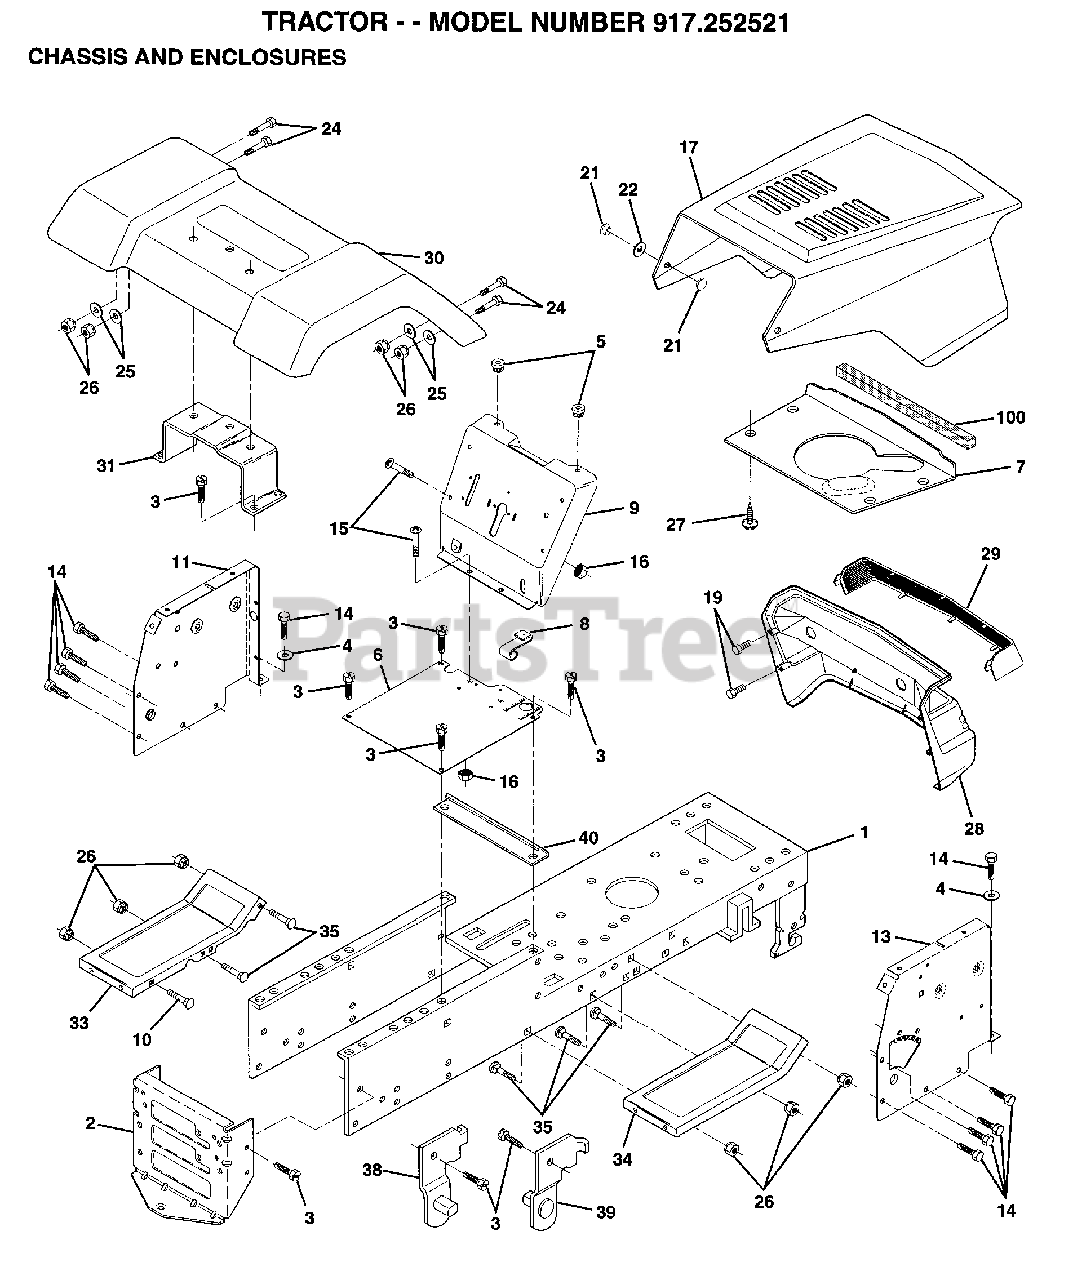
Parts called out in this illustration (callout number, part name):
1	CHASSIS.WLD.11GA
3	SCREW
4	WASHER
7	"SHIELD,HEAT HOOD"
8	"CLIP,INSULATOR"
11	DASH PANEL LH
14	SCREW LT
15	SCREW
19	SCREW SLTD HXHD
21	"RIVET,PLASTIC"
25	WASHER
31	BRACKET SUPT FEND
33	FOOTREST.LH.LT-GT
34	FOOTREST.RH.LT-GT
38	BRACKET ASM LH
39	BRACKET ASM RH
40	SPACER FENDER LT
100	FOAM-STRIP LT
